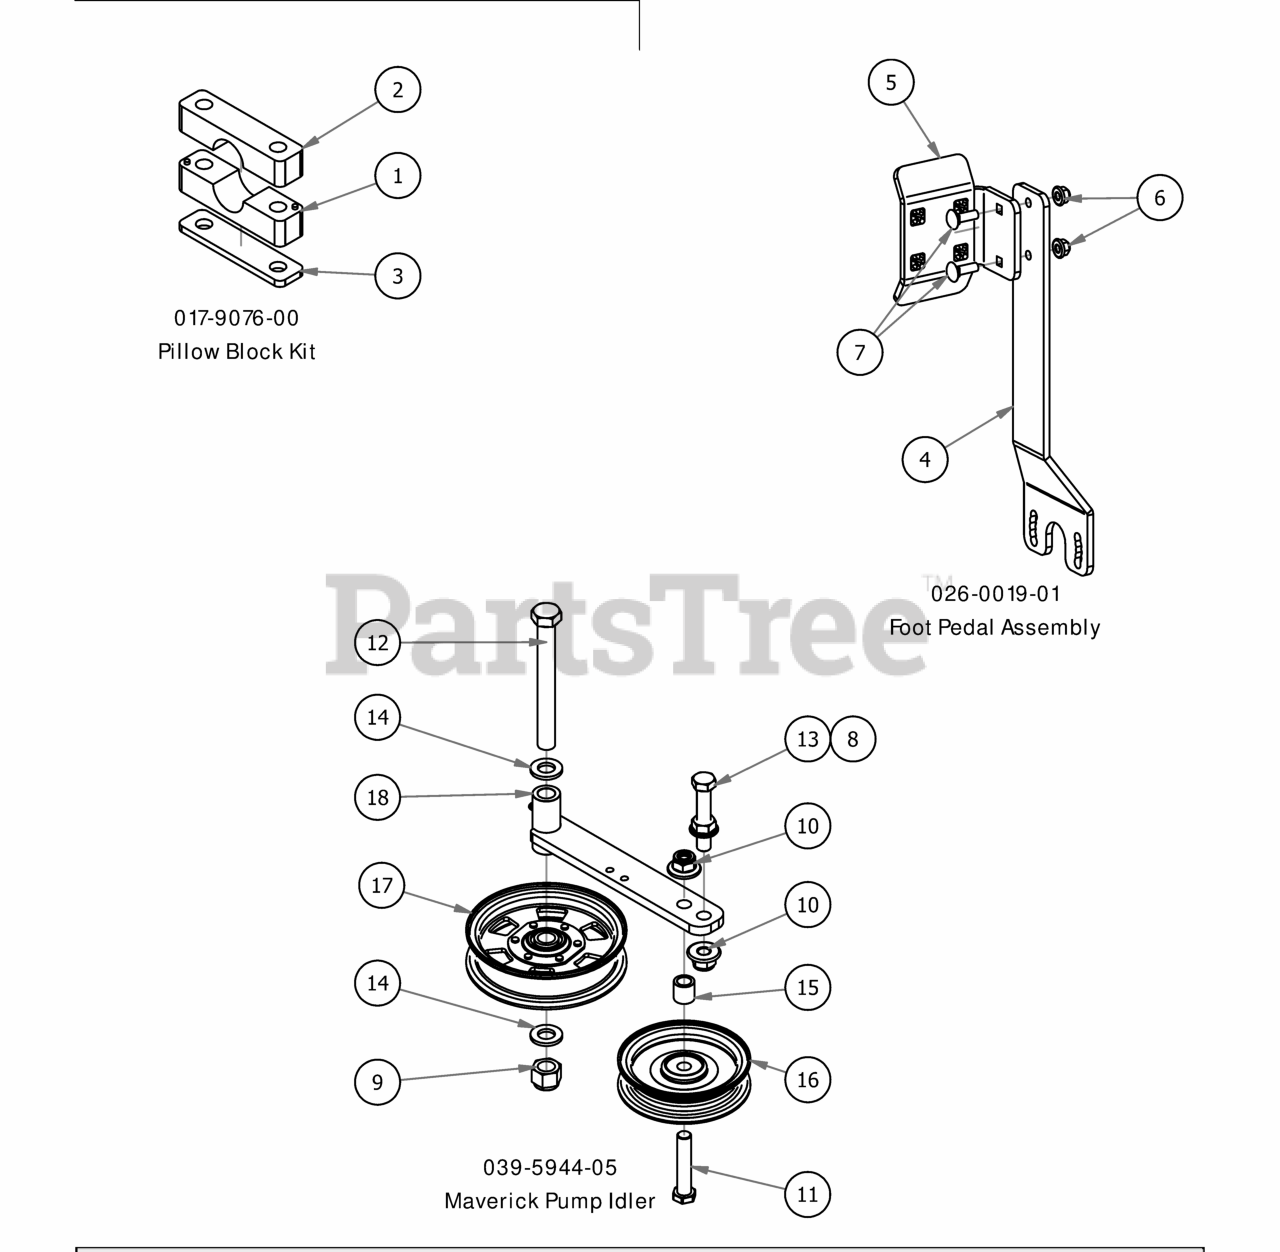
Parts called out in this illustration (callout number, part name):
1	Pillow Block MZ male
2	Pillow Block MZ female
3	Pillow Block Strap
4	2017 MZ/ZT Deck Pedal Lever
5	2017 MZ/ZT Shallow Foot Pedal
6	5/16" Nylon Flange Nut
7	5/16" x 1" Carriage Bolt
8	1/2" Flange Nut
9	5/8 Std NC Nylock Nut
10	1/2-13 Nylon Flange Nut
11	1/2" x 3" Hex Bolt
12	5/8" x 5 1/2 Hex Bolt
13	1/2" x 2 3/4" Hex Bolt
14	.630 ID Plastic Washer
15	Spacer 3/4 OD x 1/2 ID x 3\4 Length
16	4 3/4" Idler Pulley
17	5 3/4 Idler Pulley, 5/8 Bore
18	Deck Idler
